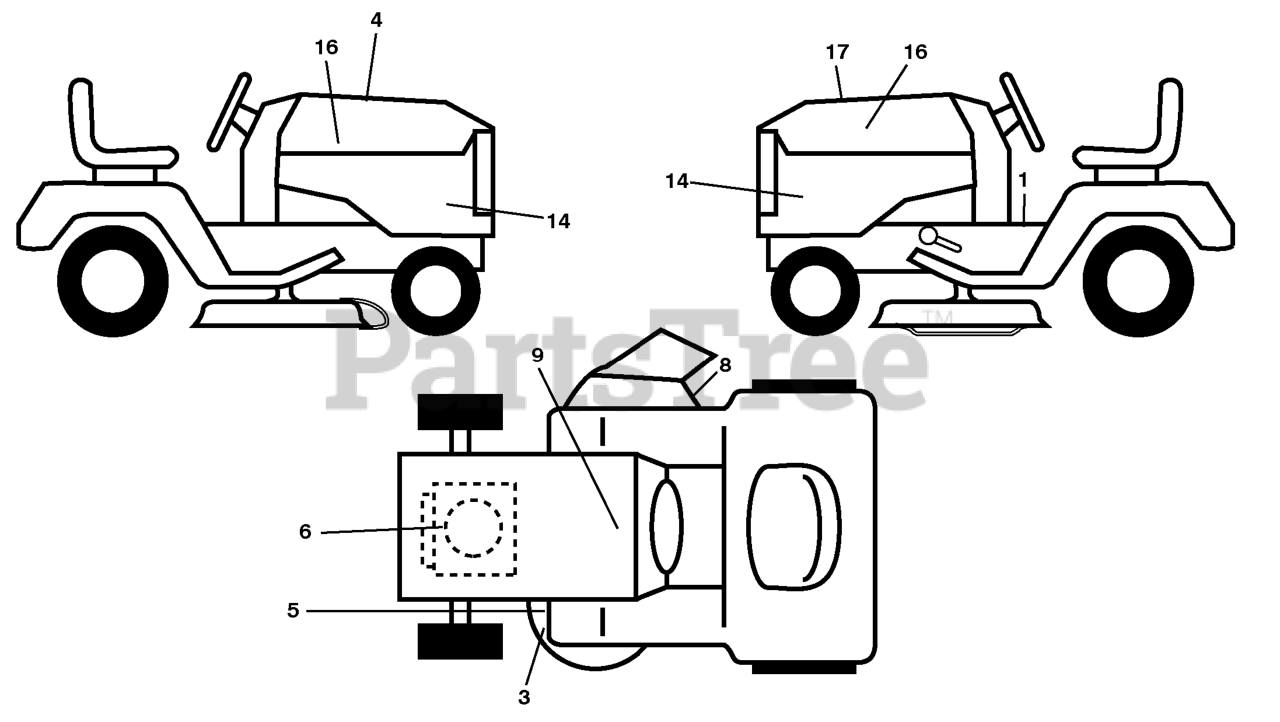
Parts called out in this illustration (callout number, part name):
1	DECAL.FENDER.WARNING.ENG
3	DECAL.WARN.KEEP.HAND.AWAY
4	DECAL.WARNING.CUST.RESP.E85.
5	DECAL.MOWER
6	DECAL, ENGINE, HP
8	DECAL.MOWER.SCH.48/54
9	DECAL BTRY SYMBOLS
14	DECAL SDPNL.YTH24V54.B&S.HUSQ
16	RP.DECAL.BADGE.170MM.TEXTLOGO
